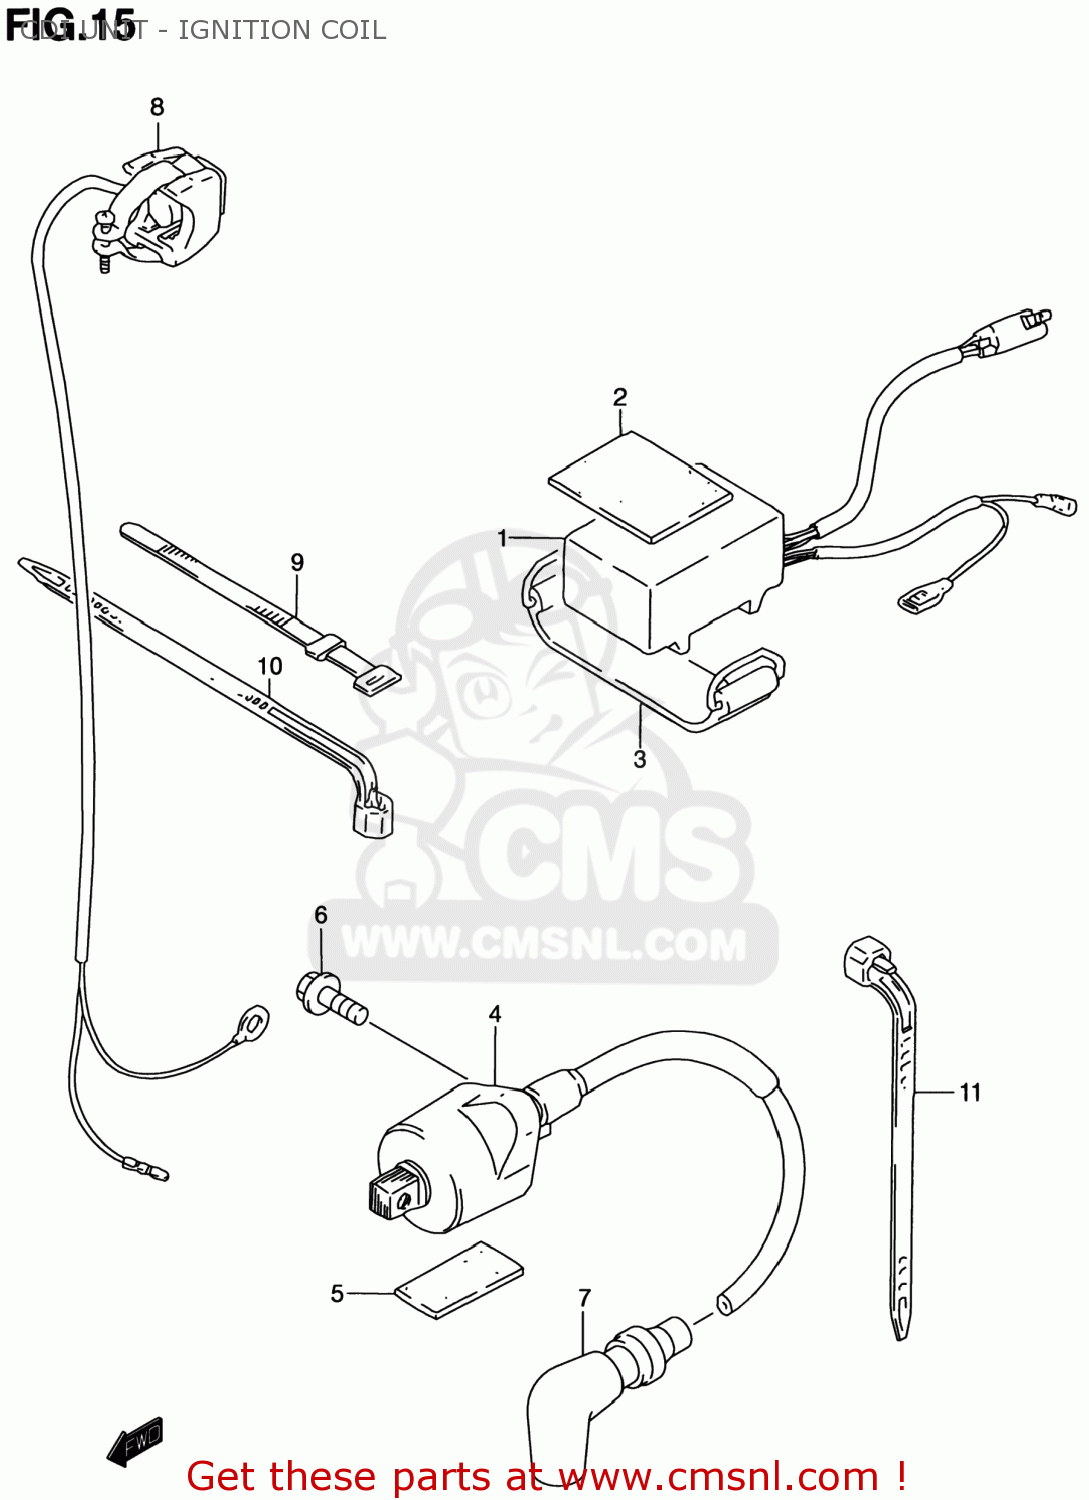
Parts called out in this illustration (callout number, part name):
1	CDI UNIT
2	PROTECTOR(170X95X3.0)
3	BAND
4	COIL ASSY,IGNITION
5	PROTECTOR(170X95X3.0)
6	SCREW
7	CAP,SPARK PLUG
8	SWITCH ASSY,ENGINE STOP
9	CLAMP(L:120)
10	CLAMP(L:165)
11	CLAMP(L:125)
